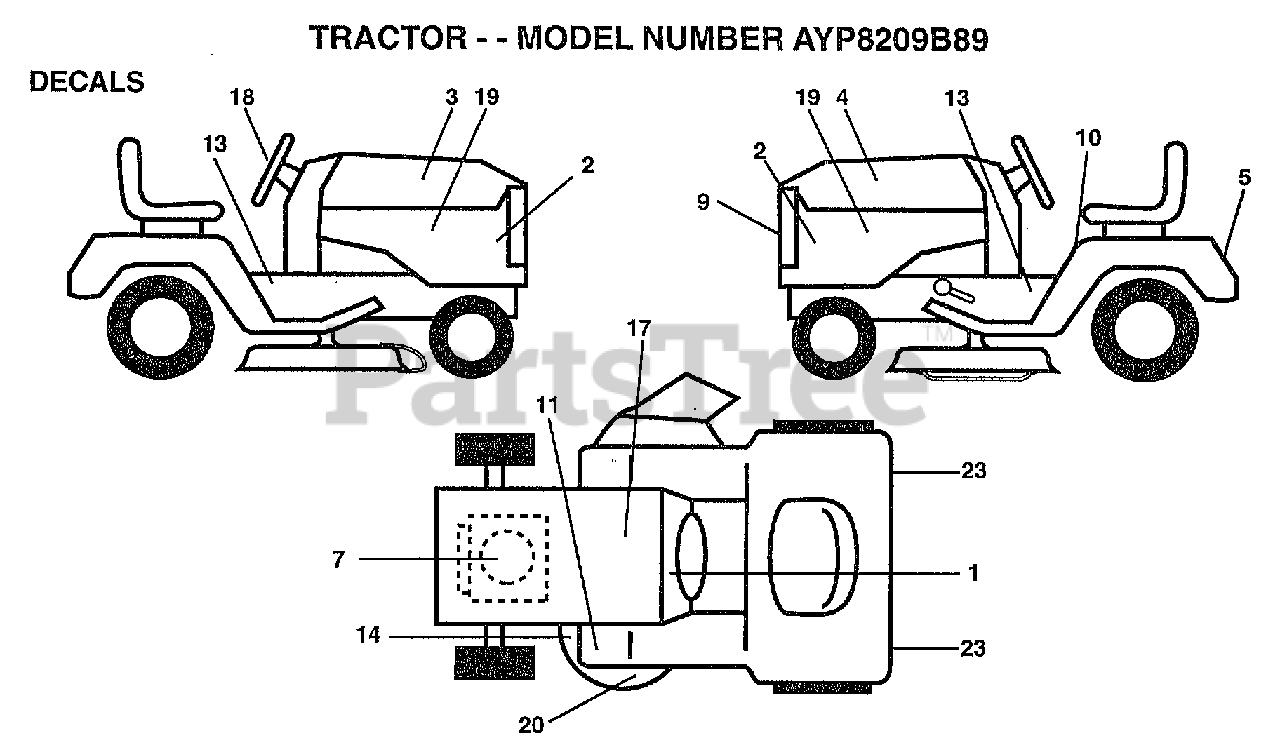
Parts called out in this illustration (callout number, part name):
1	"DECAL-OPER,GEAR D"
2	NAMEPLATE.HD.WIZA
3	DECAL.HD.RH.WIZRD
4	DECAL.HD.LH.WIZRD
6	DECAL.GRILLE.WIZ+
7	DECAL, ENGINE
9	DECAL.GRILLE.WIZ+
10	"DECAL DANGER,FEND"
13	"DCL.CHASSIS.50"""
17	DECAL.BATRY.3-3908
18	DECAL INS STG WHL
19	DECAL.PANEL.SIDE
20	DECAL DECK WIZ +
23	REFLECTOR-TAIL YT
